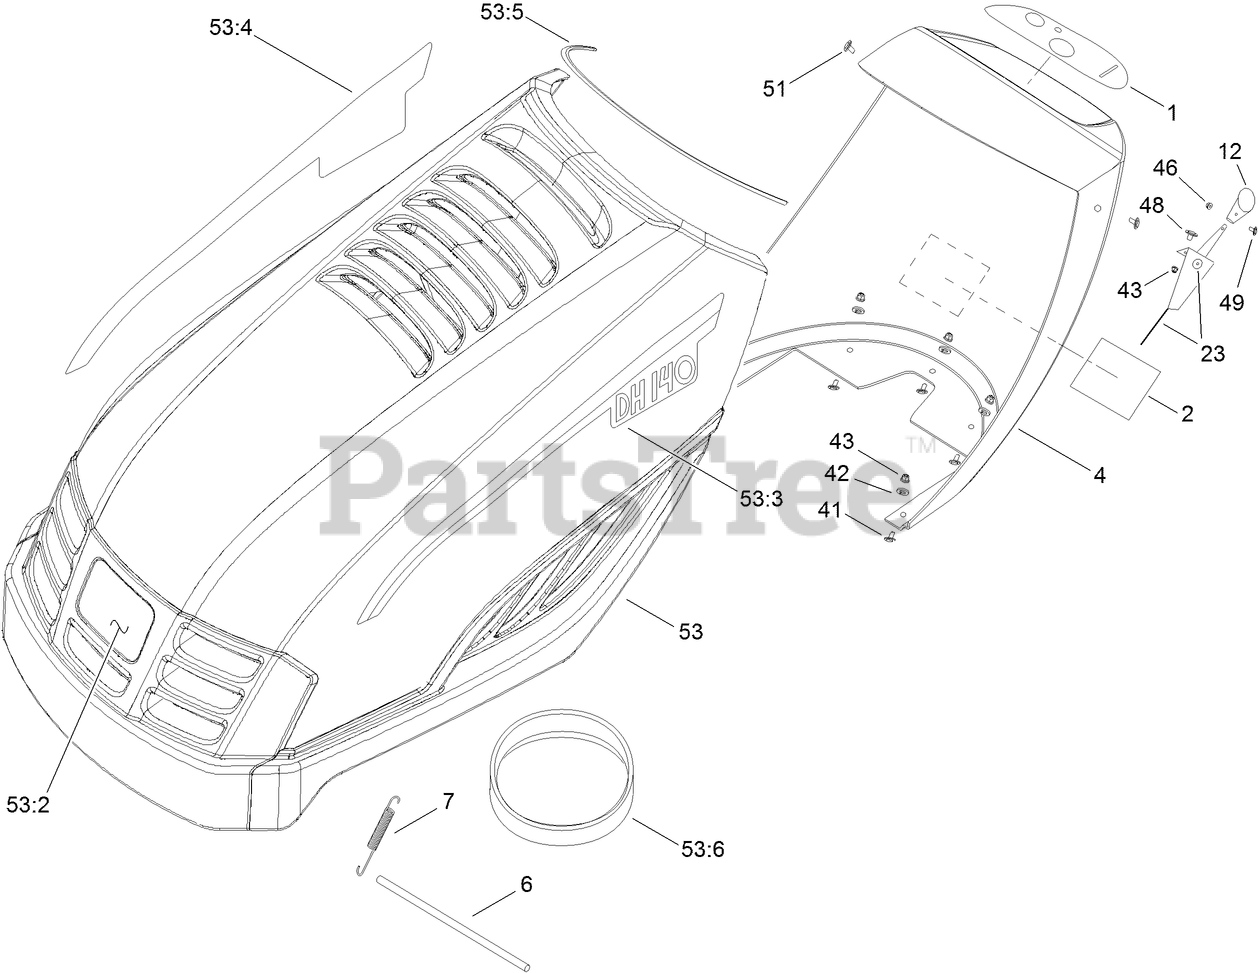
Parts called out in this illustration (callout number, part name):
1	DECAL-PANEL
4	PANEL-DASH
6	BAR-SAFETY
7	SPRING-HOOD
12	KNOB-THROTTLE/CHOKE
23	CABLE-THROTTLE/CHOKE
41	SCREW-HEX
42	WASHER-FLAT
43	NUT-LOCK
46	NUT-HEX
48	SCREW-FLAT HEAD
53	HOOD ASM
53:3	DECAL-DH 140 (LH)
53:4	DECAL-DH 140 (RH)
53:5	RUBBER-PURL
53:6	GASKET-FOAM
